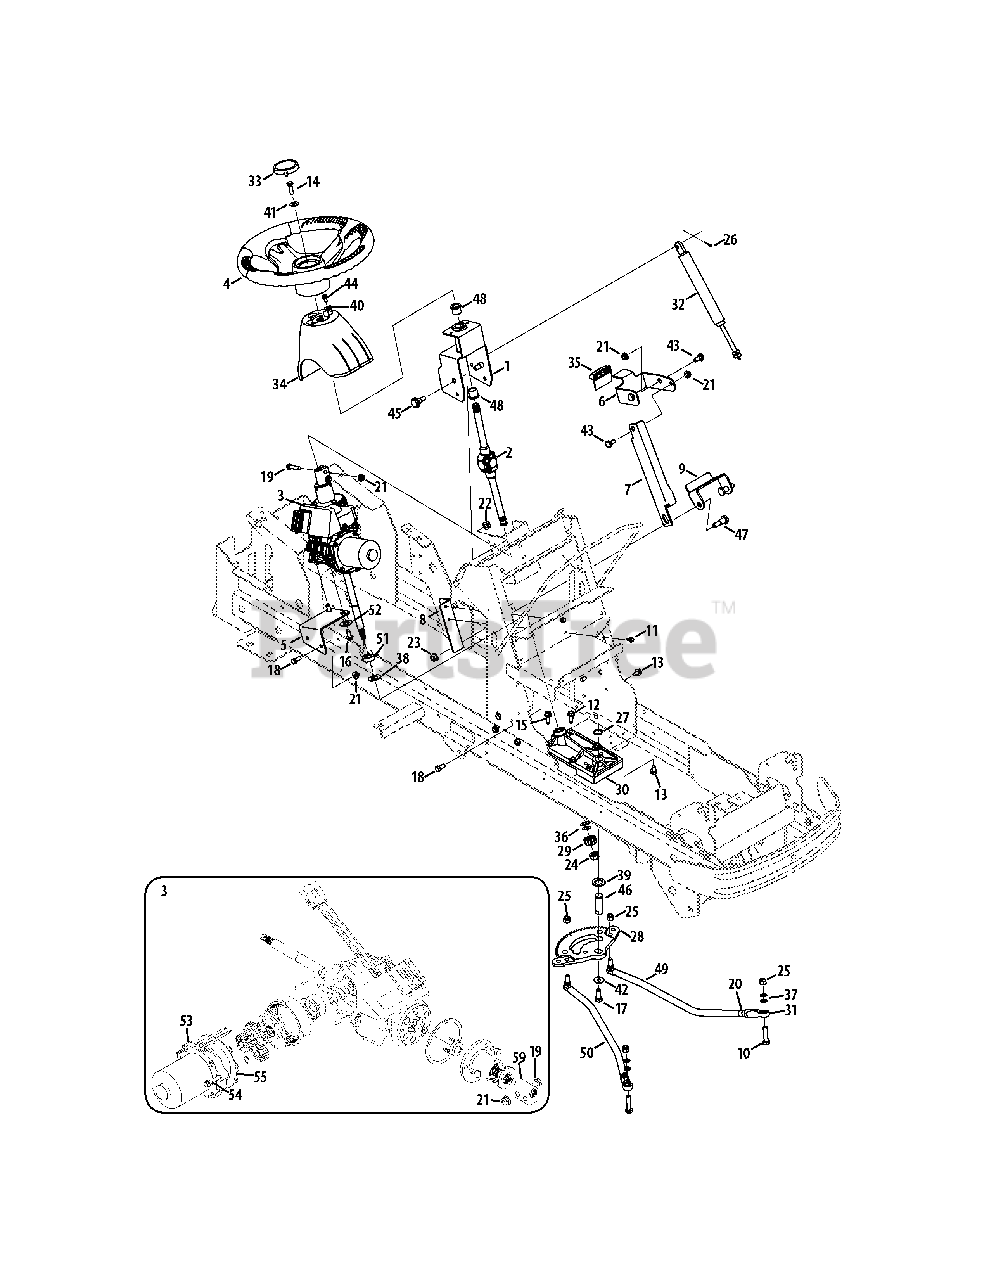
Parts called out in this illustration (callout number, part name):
1	Upper Steering Support Bracket
2	Power Steering Assembly
3	Transmission Assembly
4	Steering Wheel
5	Power Steering Mount Box
6	Tilt Steering Lever Bracket
7	Tilt Steering Bracket
8	Tilt Steering Mount Bracket
9	Tilt Steering Pivot Bracket
10	Hex Screw, 3/8-24 x 1.75
11	Hex Washer Screw, 1/4-20 x .500
12	Hex Washer Screw, 5/16-18 x 1.000
13	Hex Washer Screw, 5/16-18 x .625
14	Hex Lock Screw, 5/16-18 x 1.00
15	Hex Washer Screw, 5/16-18 x 1.250
16	Hex Washer Screw, 5/16-18 x .750
17	Hex Screw, 5/16-18 x .75
18	Hex Screw, 5/16-18 x .75
19	Hex Screw, 5/16-18 x 1.375
20	Jam Nut, 7/16-20
21	Flange Lock Nut, 5/16-18
22	Flange Lock Nut, 3/8-16
23	Flange Lock Nut, 3/8-16
24	Flange Lock Nut, 7/16-20
25	Hex Lock Nut, 3/8-24
26	Cotter Pin, 3/32 x .750
27	Snap Ring, .750
28	Segment Gear
29	Pinion Gear
30	Steering Housing
31	End Rod, 7/16-20 x 3/8
32	Locking Damper Cylinder
34	Dash Collar
35	Tilt Lever
36	Flat Washer, .510 x .750 x .033
37	Flat Washer, .385 x .62 x .063
38	Flat Washer, .64 x 1.24 x .06
39	Flat Washer, .76 x 1.49 x .06
40	Flat Washer, .344 x .62 x .033
41	Bell Washer, .340 x .872 x .060
42	Flat Washer, .344 x 1.00 x .063
43	Shoulder Screw, .435 x .178-5/16 x .56
44	Shoulder Screw, 1/4-20 x 0.500
45	Shoulder Bolt, 3/8-16 x .49 x .33
46	Steering Shaft
47	Shoulder Screw, 3/8-16 x .50 x .66
48	Flange Bearing, .630
49	LH Drag Link, 5/8
50	RH Drag Link, 5/8
51	Ring Spacer Hub
52	Flat Washer, .344 x 1.000 x .063
53	Electric Motor
54	Hex Washer Screw, 1/4-20 x 1.250
55	Motor Gasket
59	Steering Shaft Coupler
